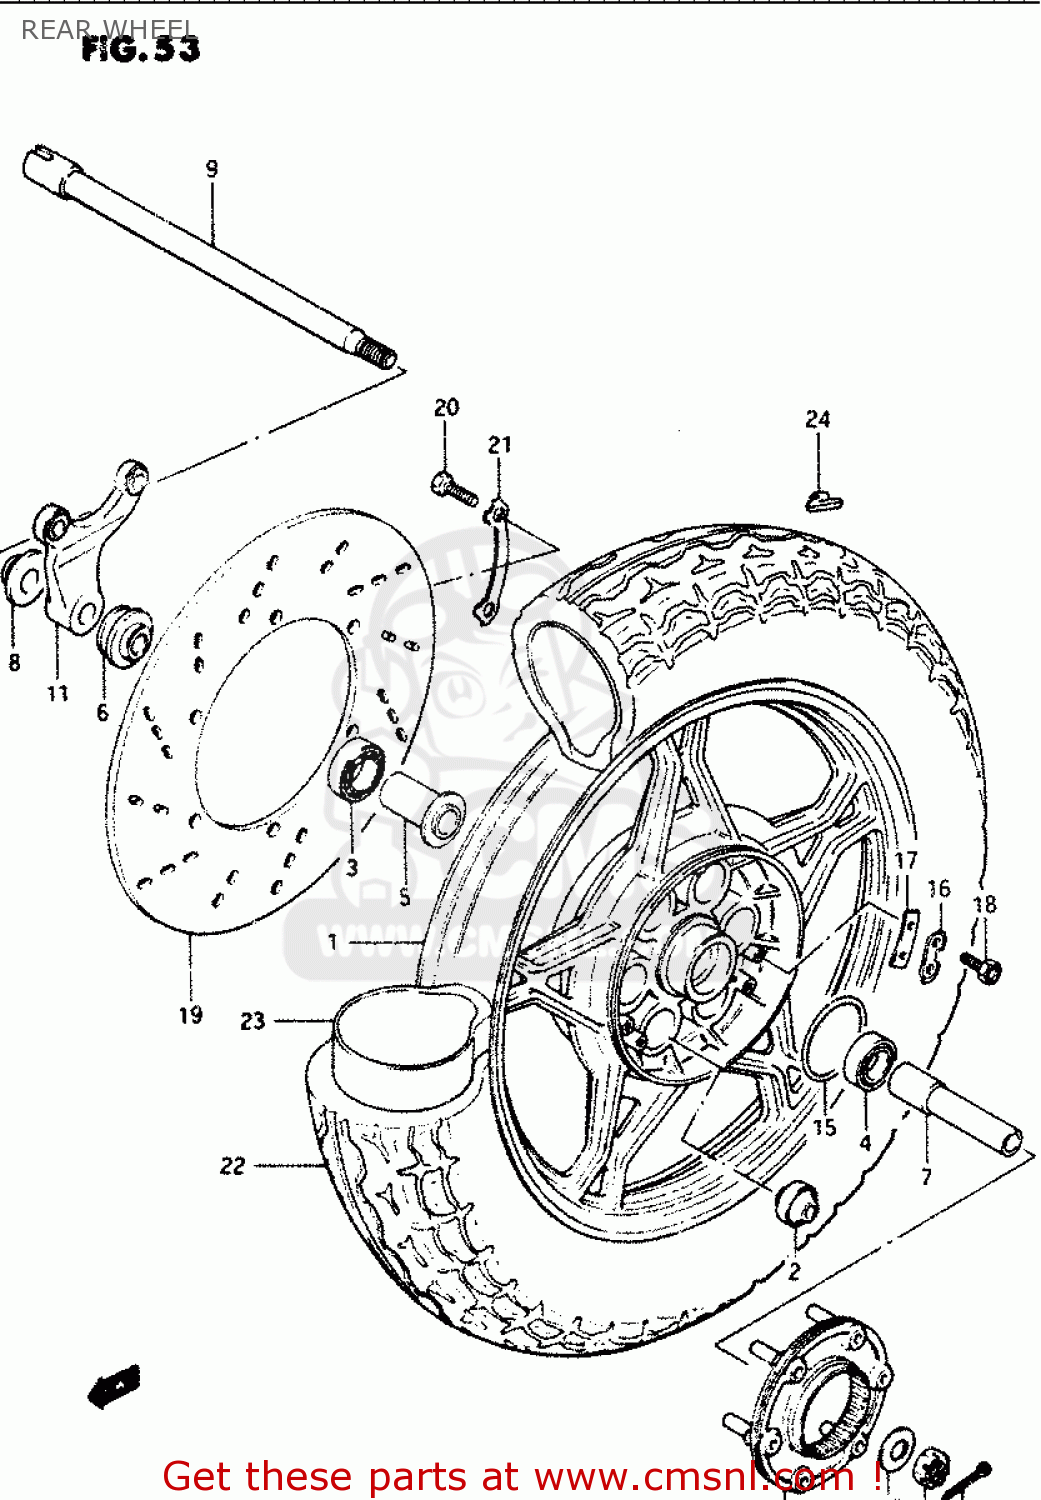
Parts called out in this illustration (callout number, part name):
1	CASTING WHEEL,REAR 2.50
2	BUSH
3	BEARING
4	BEARING
5	SPACER,REAR HUB BEARING
6	SPACER,REAR CALIPER BRACKET
7	SPACER,REAR AXLE,LEFT
8	SPACER,REAR AXLE,RIGHT
9	AXLE,REAR
10	NUT
11	BRACKET,RR,CALIPER
12	PIN,COTTER
13	WASHER (17.5X36X3.2)
14	JOINT ASSY,RR HUB DRIVEN
15	O RING(D:2.1,ID:65)
16	WASHER
17	WASHER,THRUST(T:1.6)
18	BOLT(6X16)
19	DISC,RR BRAKE
20	BOLT(8X25)
21	WASHER
22	TIRE 4.50V17
23	TUBE ASSY,WHEEL INNER
24	BALANCER,WHEEL
